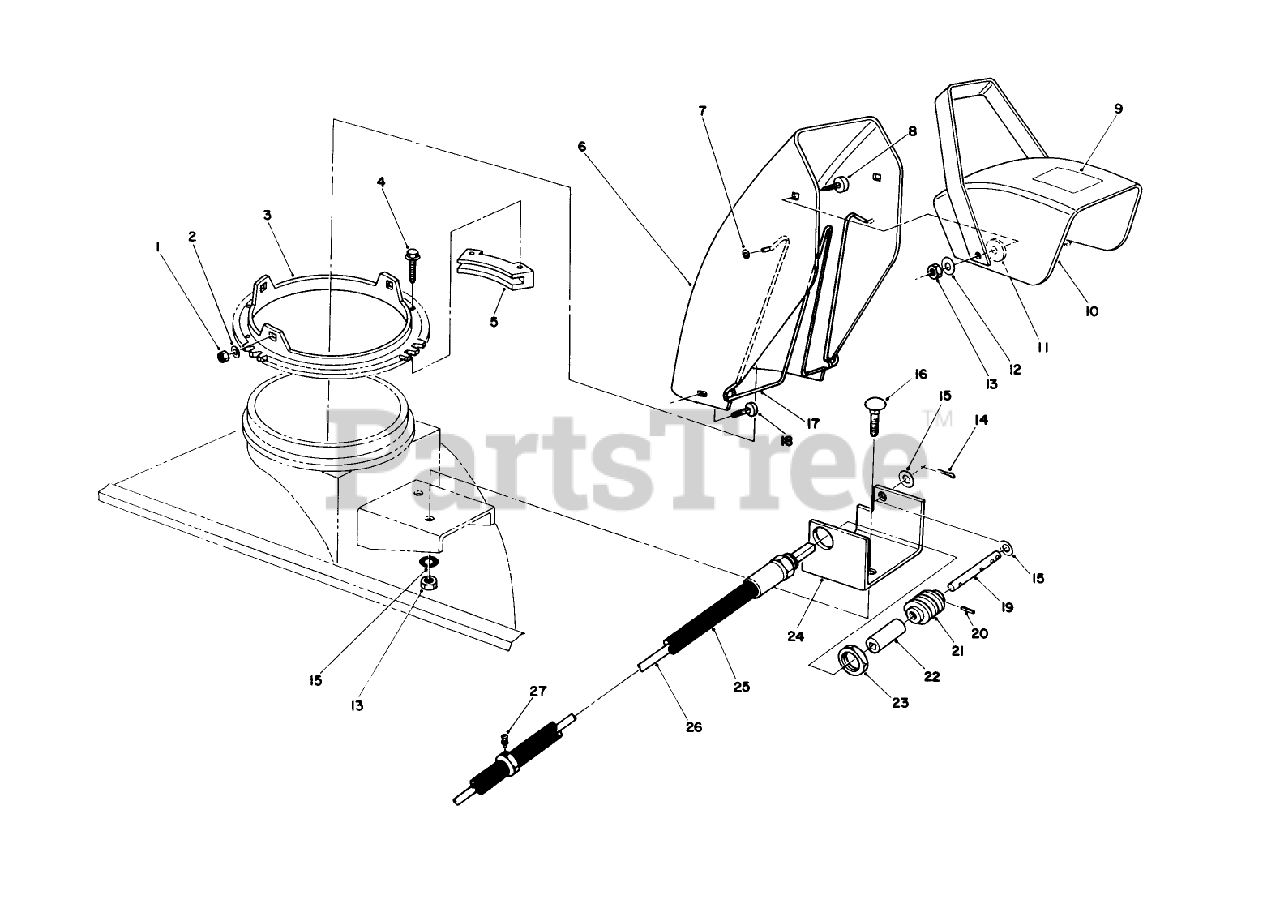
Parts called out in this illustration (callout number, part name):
1	NUT-LOCK, NI
2	WASHER-PLAIN
3	Screw
4	SCREW-SPECIAL
5	RETAINER-CHUTE
6	Chute-Upper
7	NUT-PUSH
8	SCREW-CARR
9	Decal-Discharge
10	Deflector
11	WASHER-RUBBER
12	WASHER-BELLEVILLE
13	NUT-LOCK
14	PIN-COTTER
15	WASHER-FLAT
16	BOLT-CARR
17	CHUTE WIRE
18	SCREW-CARR
19	SHAFT-GEAR, WORM
20	PIN-SPRING
21	GEAR-WORM, CHUTE
22	COUPLER
23	LOCKNUT
24	WORM GEAR BRKT R
25	HOSE ASM
26	FLEX SHAFT
27	FITTING-GREASE
